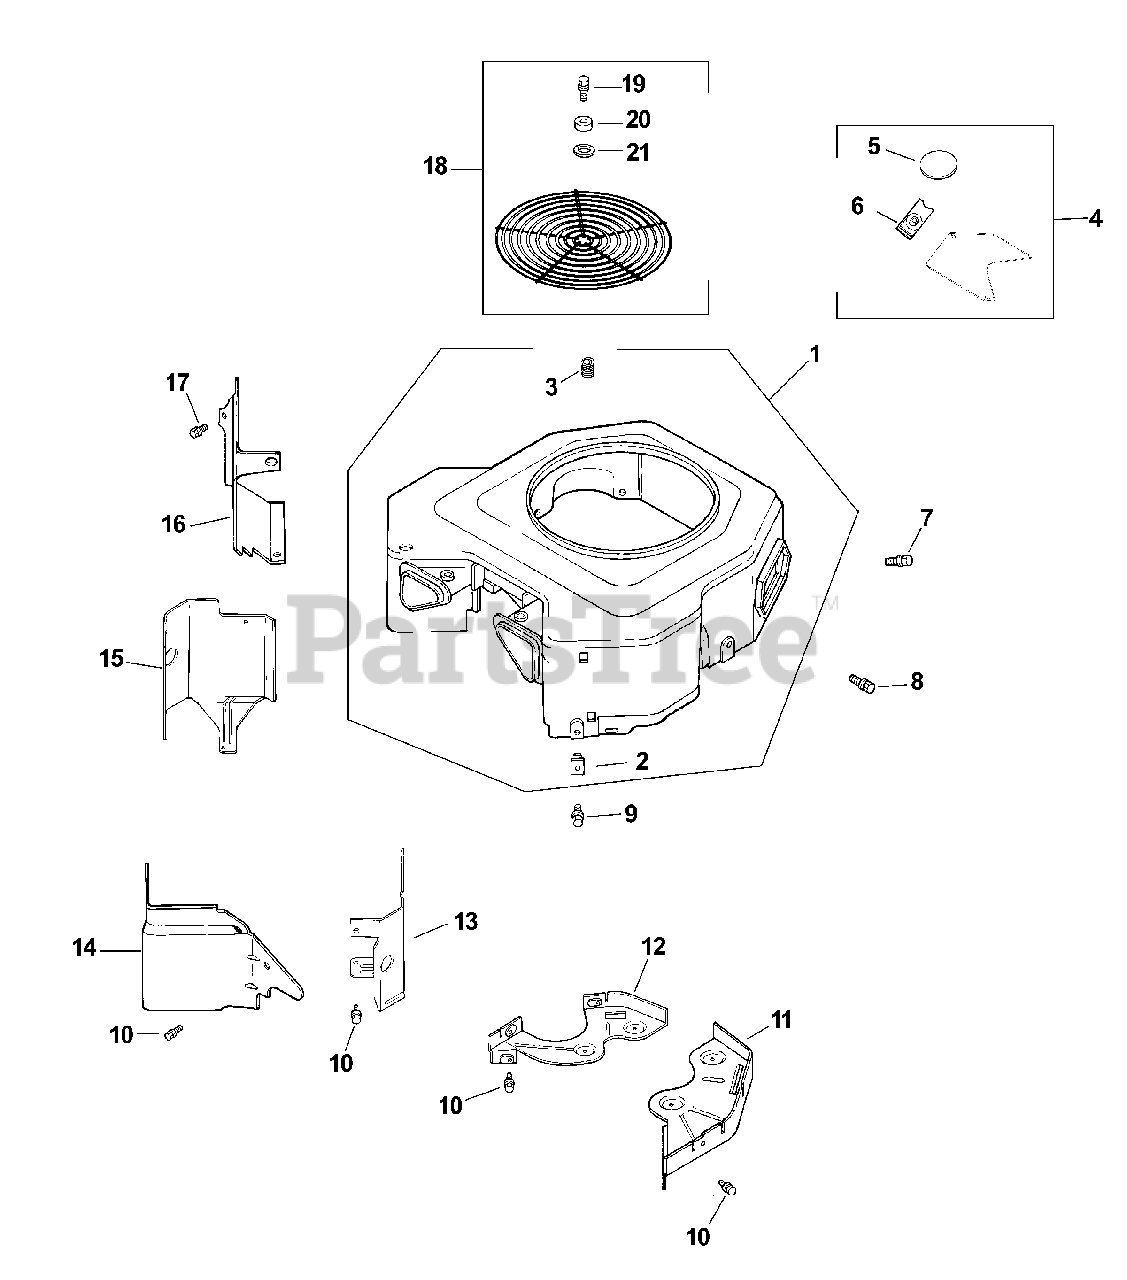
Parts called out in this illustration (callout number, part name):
1	KIT, BLOWER HOUSING ASSEMBLY USE 24 027 448-S
2	NUT, PLASTIC
3	SCREW, SKT SET #10-24X1/4"
4	KIT, ACCESS PANEL
5	PLUG, BUTTON 9/16
6	CLIP, MOUNTING-USE 25 154 13-S
7	SCREW, HVY FLG M5X.8X16
8	SCREW,FLG THD FRM M5X0.8X16-(#25086398S)
9	SCREW, FLG THD FRM M5X.8X20-(#25086399S)
10	SCREW,FLG THD FRM M6X1.0X16-(#25086397S)
11	PLATE, BACKING - #2 SIDE-USE 24 146 59-S
12	PLATE, BACKING - DISCONTINUED
14	BAFFLE, VALLEY #2 SIDE-USE 24 063 94-S
15	BAFFLE, RIGHT BARREL-USE 24 063 85-S
16	BAFFLE, VALLEY (CV)-USE 24 063 93-S
17	SCREW, FLG THD FRM M5X.8X10
18	KIT, GUARD
19	SCREW, PAN HEAD-USE 25 086 160-S
20	SPACER USE 25 112 30-S
21	WASHER, FLAT 7/32"
